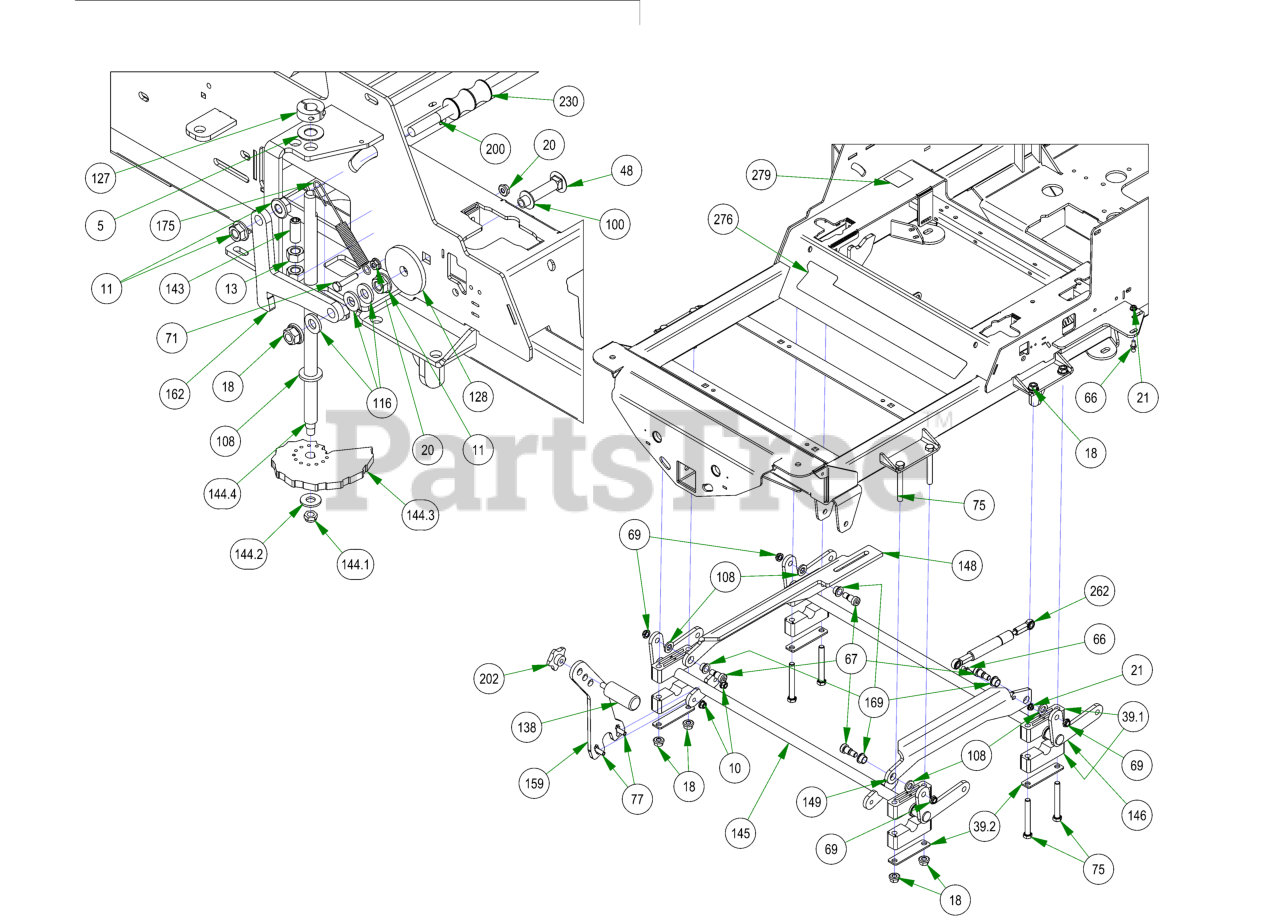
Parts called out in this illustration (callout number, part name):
5	.625 ID x 1.250 OD x .062 THK F/W Nylon
10	3/8-16 NYLON INSERT FLANGE LOCKNUT (GR.F) ZINC
11	1/2-13 HEX SERRATED FLANGE NUT HARD/ZINC
13	1/2-13 HEX NUT ZINC
18	1/2-13 NYLON INSERT FLANGE LOCKNUT ZINC
20	1/4-20 HEX SERRATED FLANGE NUT HARD/ZINC
21	5/16-18 HEX SERRATED FLANGE NUT HARD/ZINC
39	Pillow Block Assembly
39.1	Two Piece Pillow Block
39.2	Two Piece Pillow Block Strap
48	2 1/2 x 1/2 Carriage Bolt
66	10mm Damper Ball Stud-XP Linkage
67	5/8 X 5/8 SOCKET SHOULDER BOLT ZINC YELLOW
69	1/2-13 NYLON INSERT JAM LOCKNUT ZINC
71	1/4-20 X 1-1/4 HEX CAP SCREW (GR.5) ZINC
75	1/2-13 X 4 HEX CAP SCREW (GR.8) ZINC YELLOW
77	3/8-16 X 1-1/4 CARRIAGE BOLT ZINC
100	.517 SQ WDTH ID X .937 OD X .060 THICK F/W PHOS/OIL
108	.635 ID X 1.120 OD X .140 THICK FLAT WASHER NYLON
116	.505 ID X 1.000 OD X .125 THICK FLAT WASHER NYLON
127	5/8" Split Collar
128	MZ Deck Idler Spacer
138	Knurled Pedal
143	Dial Rod Plunger
144	2019 Outlaw Gen2 Deck Height Dial Rod Assy
144.1	3/8-24 Nylon Insert jam locknut
144.2	3/8" Flat Washer
144.3	2019 Deck Height Cam
144.4	2019 Outlaw Gen2 Dial Rod
145	2019 Outlaw Actuator - Front
146	2019 Outlaw Actuator - Rear
148	2019 Actuator Linkage – Right – Black
149	2019 Actuator Linkage - Left - Black
159	Foot Lift Upright Lever
162	2019 Outlaw Deck Travel Lock
169	.627 ID X .753 OD X .500 LGTH X 1.000 FLG OD X .094 FLG
175	Brake Spring
200	Seat Bracket Pin
202	Foot Pedal Knob 1/2-13
230	Travel Lock Rubber Grip
235	2022 Horizontal Diesel Frame
262	250lb Gas Spring - 61" Deck
276	2019 Renegade Cooler Cover Decal
279	2019 Deck Release Decal
